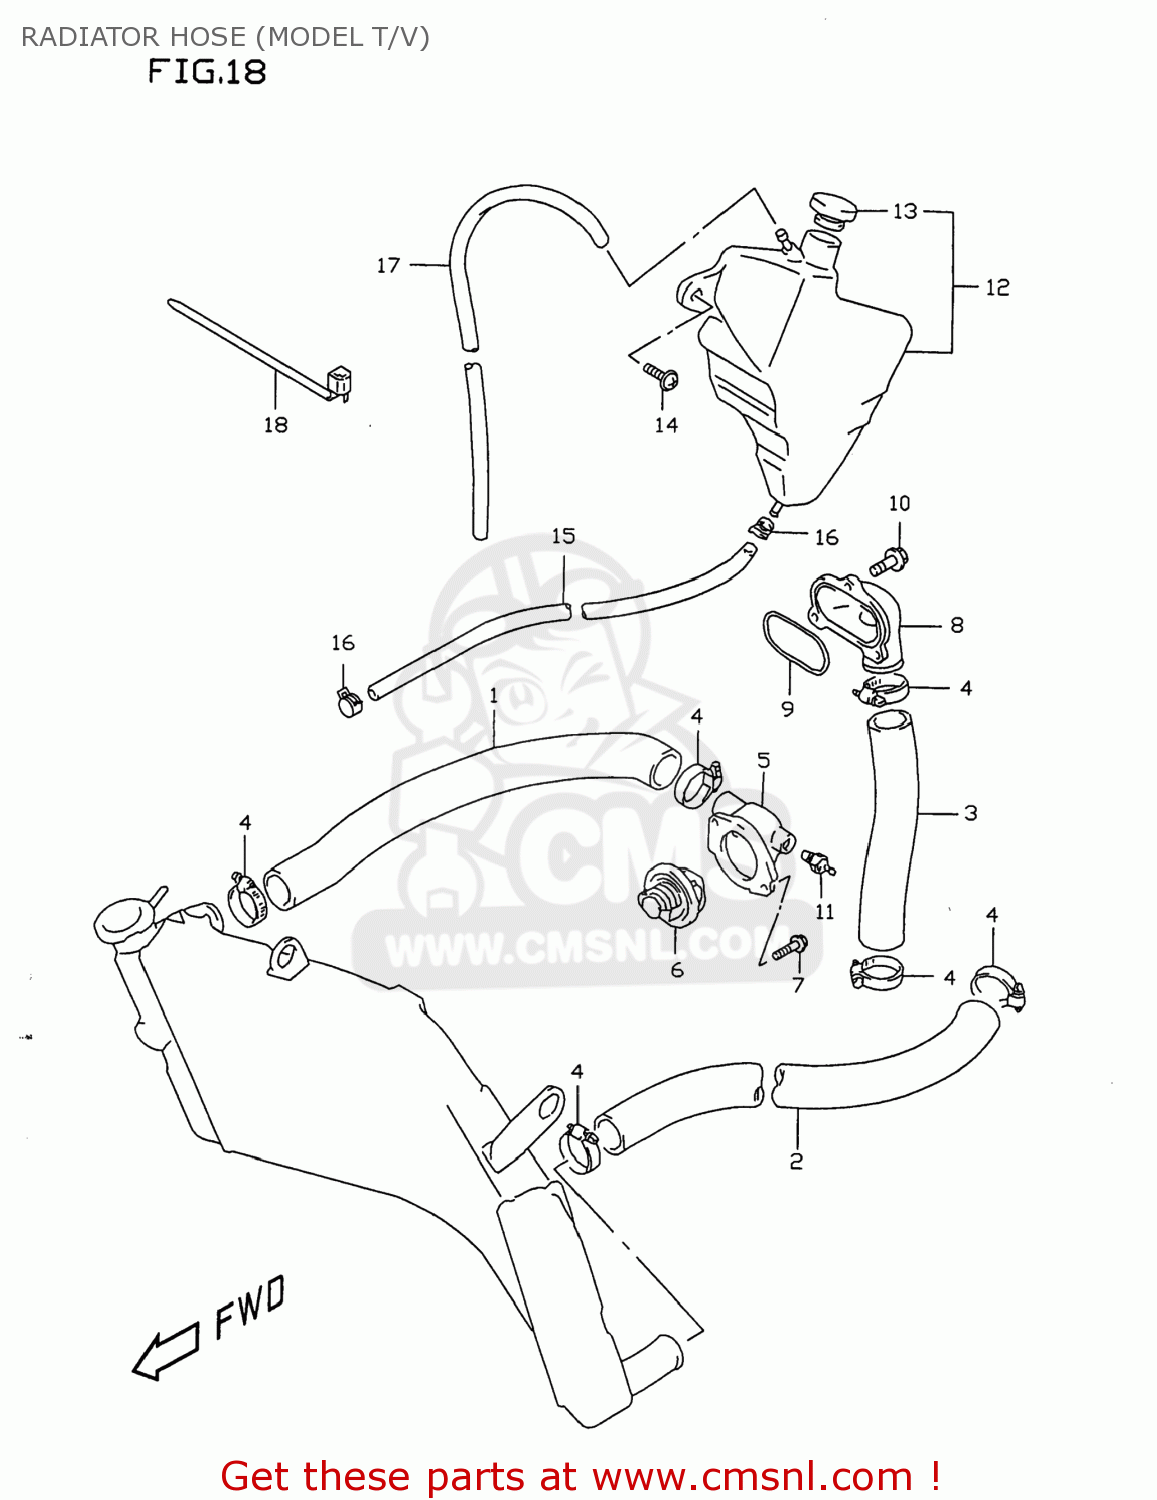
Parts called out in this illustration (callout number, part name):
1	HOSE,RADIATOR INLET
2	HOSE,RADIATOR OUTLET
3	HOSE,CYLINDER INLET
4	CLAMP
5	CONNECTOR,THERMOSTAT INLET
6	THERMOSTAT,WATER
7	BOLT
8	CONNECTOR,CYLINDER WATER,INTAKE
9	O RING,CYL WATER CONNECTOR
10	BOLT
11	GAUGE ASSY,WATER TEMP
12	TANK ASSY,RESERVOIR
13	CAP,RESERVOIR TANK
14	SCREW(6X20)
15	HOSE,RESERVOIR TANK INLET
16	CLIP
17	HOSE,RESERVOIR TANK OUTLET
18	CLAMP L:165
